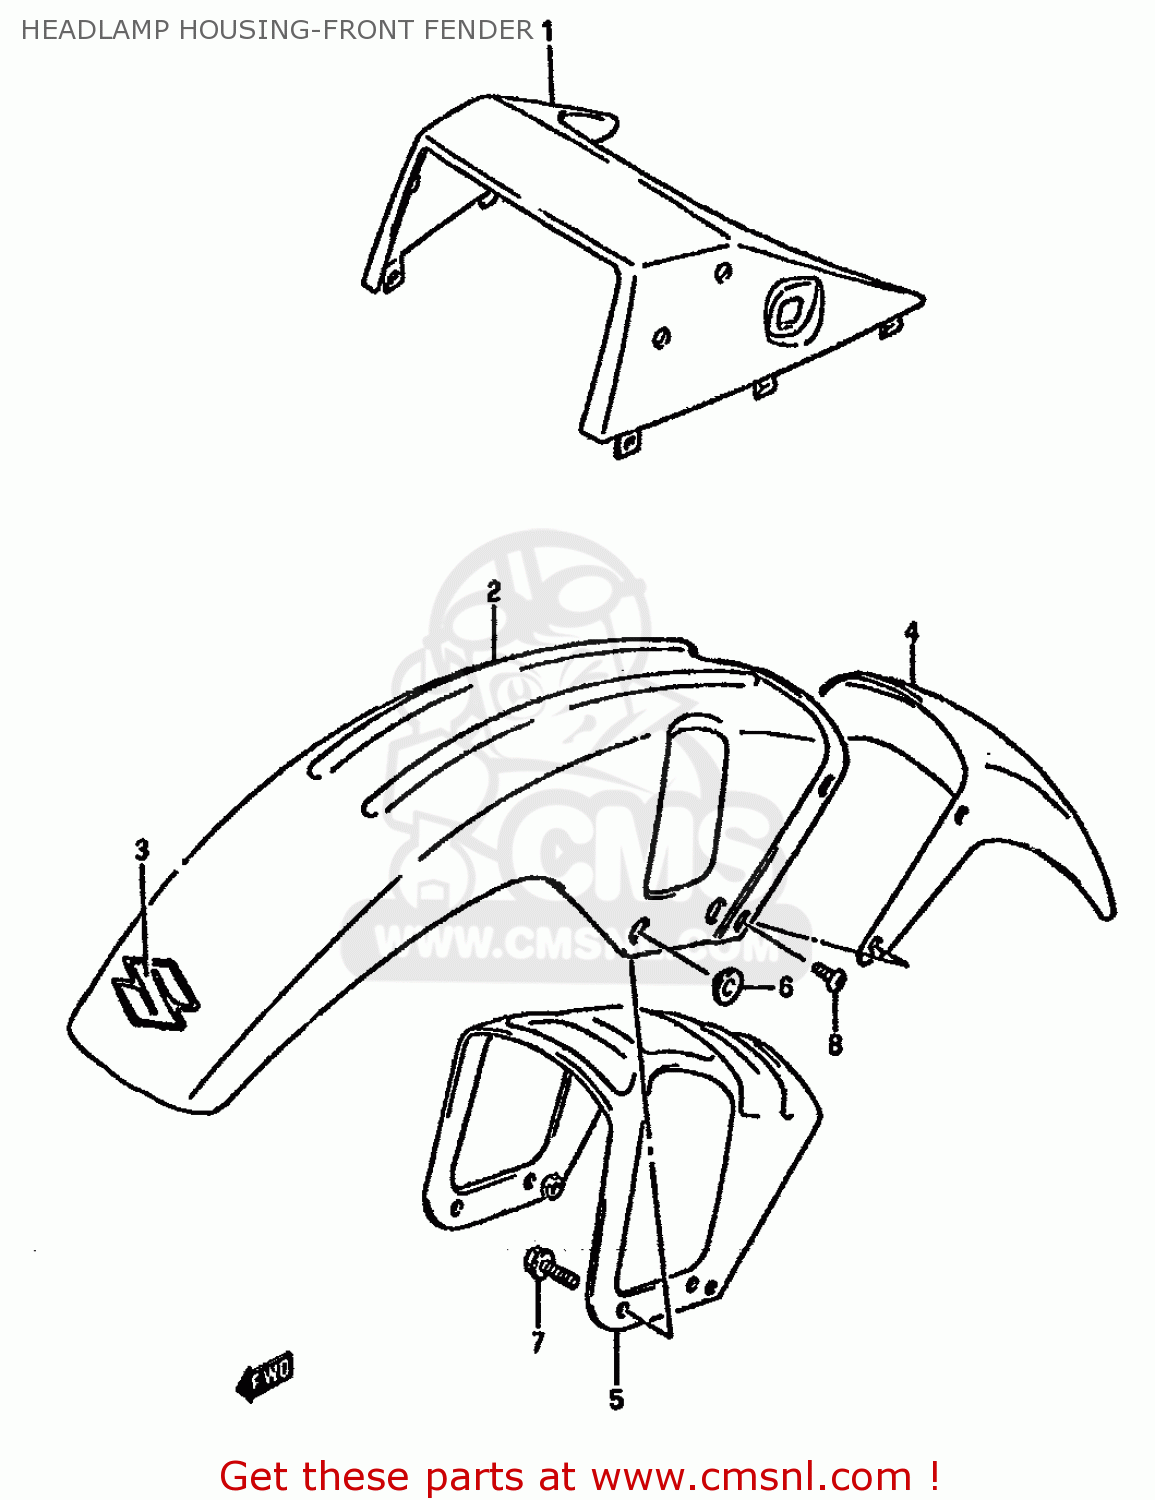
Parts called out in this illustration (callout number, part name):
1	COVER,HEADLAMP (BLACK)
2	FENDER,FR
3	EMBLEM,FRONT FENDER
4	FENDER,FR NO,2
5	BRACE, FENDER
6	WASHER
7	BOLT 6X20
8	SCREW, FRONT & REAR
